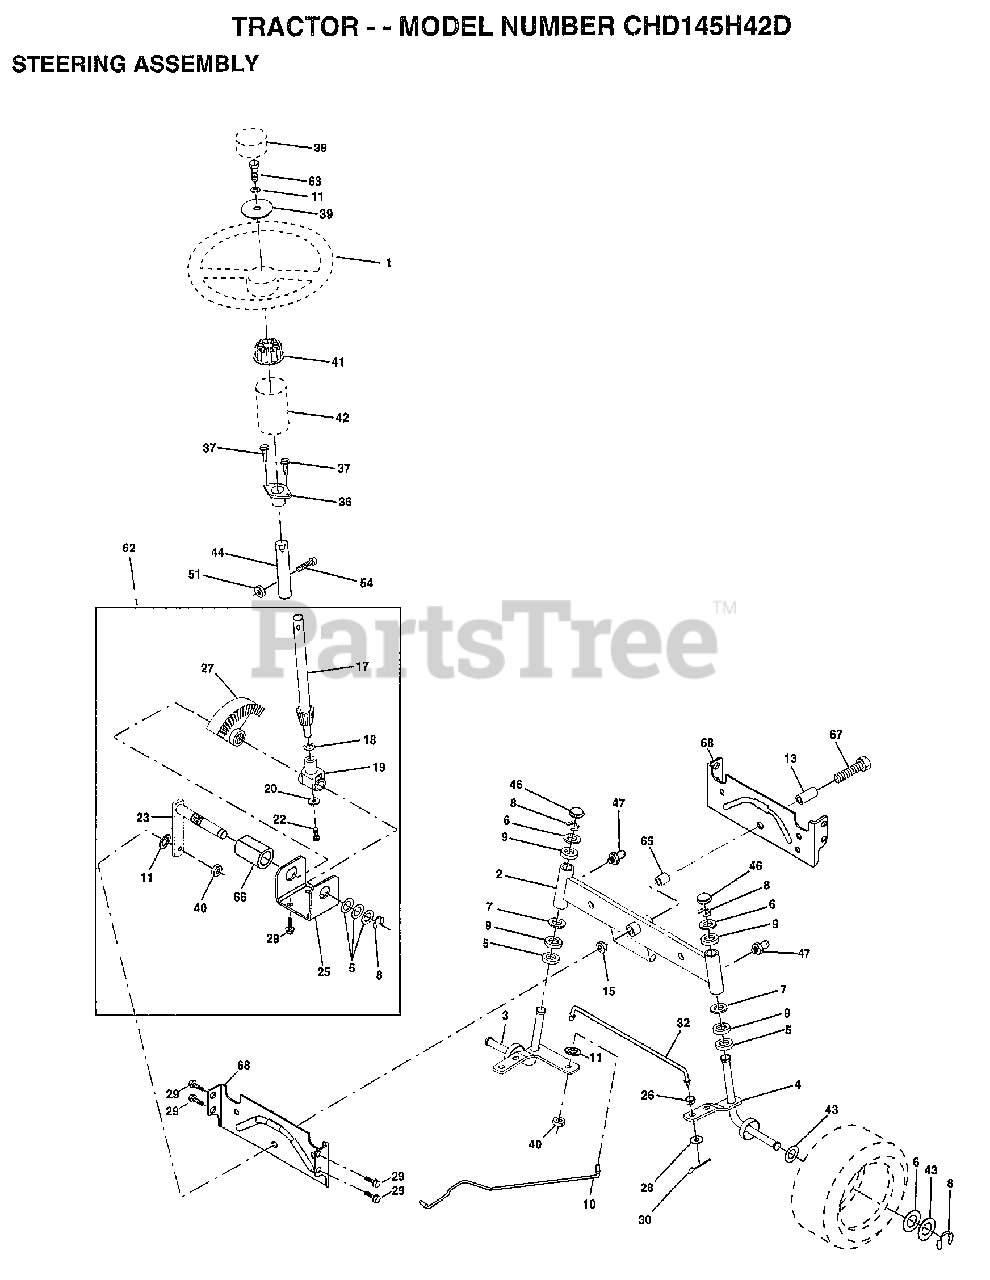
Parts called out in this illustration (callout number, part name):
1	WHEEL STR AYP BLK
2	AXLE ASM
3	SPINDLE.ASM.LH
4	"SPINDLE ASM,RH"
5	WASHER .T
6	WASHER
7	WASHER
8	RING
9	COL. SRTG. BEAR.
10	DRAGLINK-STAMPED
11	LOCKWASHER
13	BEARING AXLE
15	"NUT-LOC,FLANGE LT"
17	SHAFT ASM STEERIN
18	THRUST WASHER
19	SUPPORT.SHAFT
22	SCREW HEX SOC1/4-
25	BRKT-STEERING
26	BUSHING.DRAGLINK
27	GEAR SECTOR
28	WASHER
29	SCREW
30	COTTER PIN
32	TIE ROD
36	BUSHING.STEERING
37	"SCREW-TT,10-32 FL"
38	CAP STEER AYP
39	WASHER T
40	GRIPCO NUT
41	ADAPTER LT
42	BOOT.STEER.PL
43	WASHER
44	EXT SHAFT STEERIN
46	CAP
47	ZERK M
51	NUT
54	BOLT
62	KIT STEERING ASM
63	BOLT
65	SPACER AXLE
66	"BEARING-ARM,PITMA"
67	BOLT
68	BRACE AXLE
